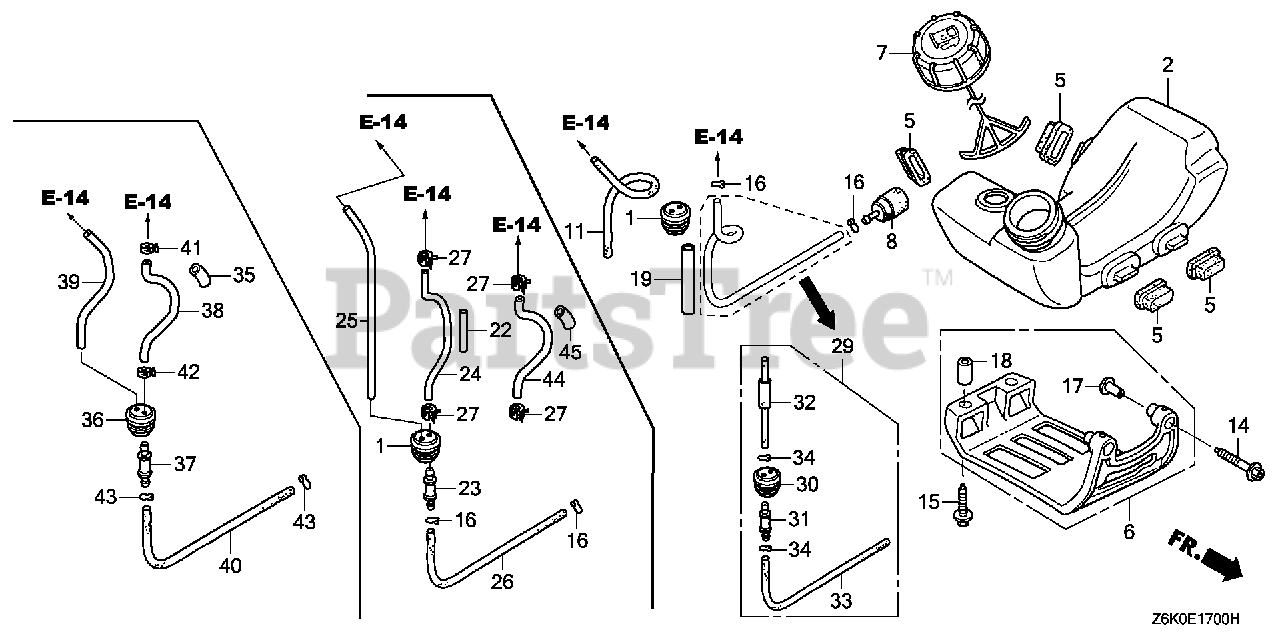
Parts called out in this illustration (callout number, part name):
2	TANK, FUEL
5	RUBBER, TANK MOUNTING
7	CAP ASSY., FUEL TANK
8	FILTER, FUEL
35	PROTECTOR, TUBE
36	GROMMET, FUEL TUBE
37	JOINT, FUEL TANK
38	TUBE, FUEL (FKM)
39	TUBE, FUEL RETURN
40	TUBE A, FUEL
41	CLAMP, TUBE (D5.5)
42	CLAMP, TUBE (D5.5)
43	CLIP, TUBE (B1 5)
